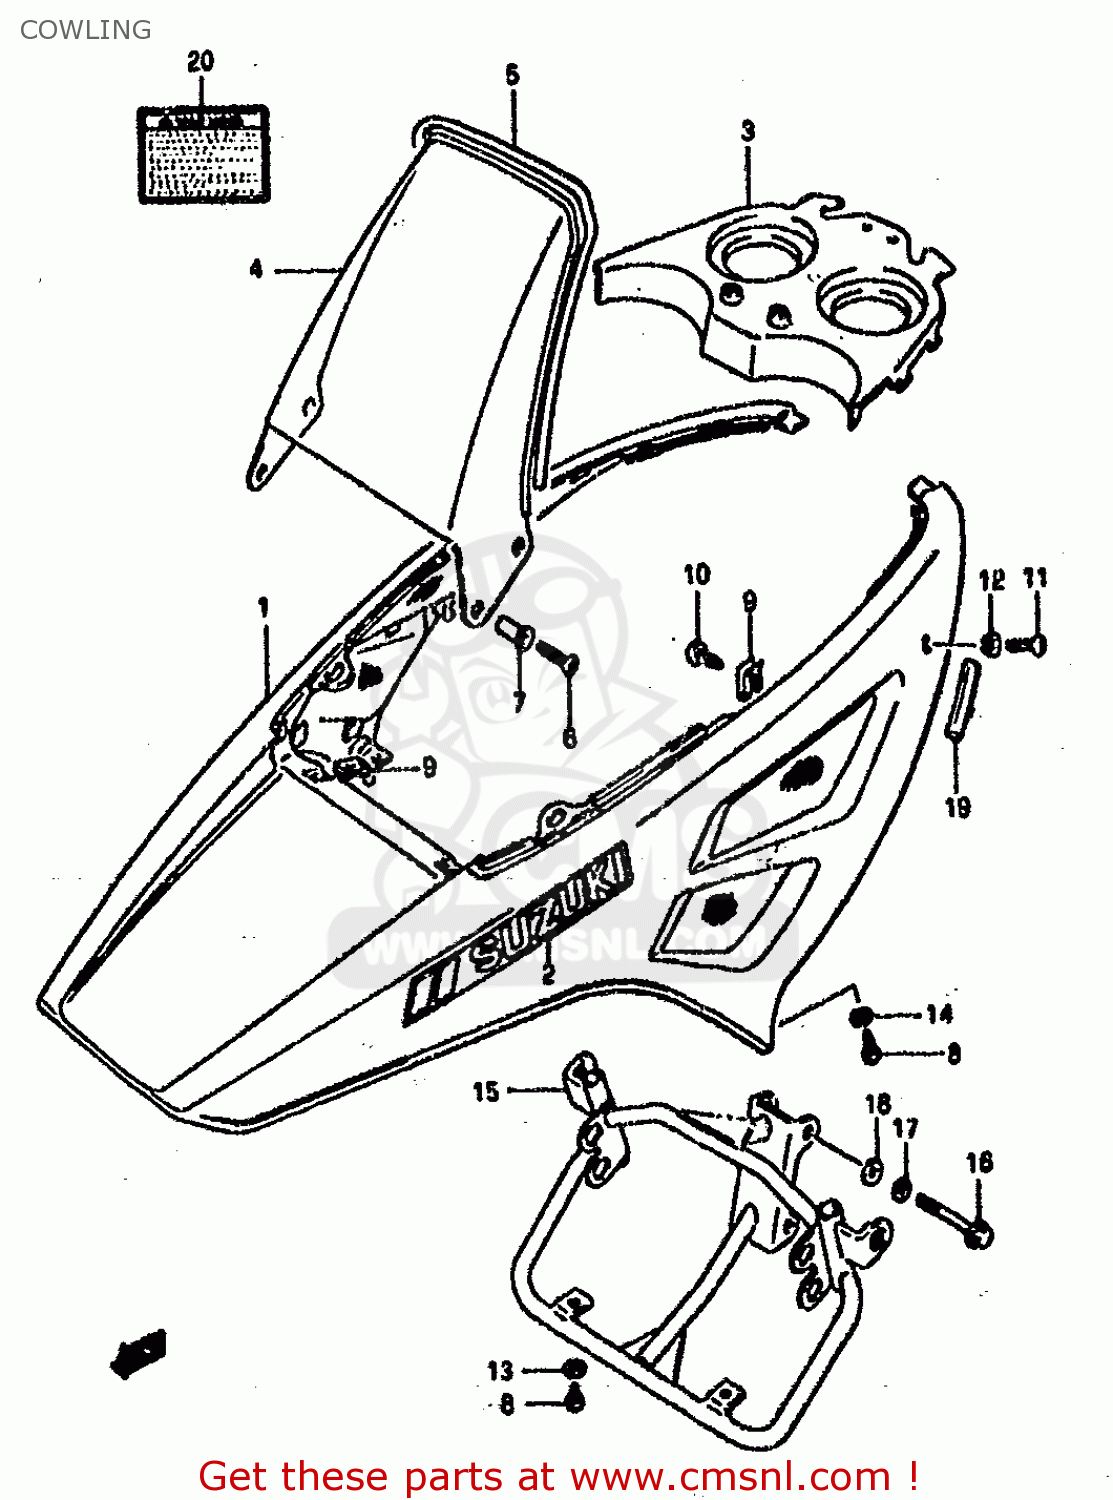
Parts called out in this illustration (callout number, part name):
1	BODY ASSY,COWLING (RED)
2	EMBLEM
3	BODY,CENTER (RED)
4	METER VISOR
5	MOLDING,VISOR
6	SCREW
7	NUT
8	SCREW
9	NUT
10	SCREW
11	SCREW
12	WASHER
13	WASHER (5.5X14X1.2)
14	WASHER (6.5X20X1.6)
15	BRACE,COWLING
16	BOLT
17	LOCK WASHER
18	WASHER
19	SEAL
20	LABEL, WARNING
